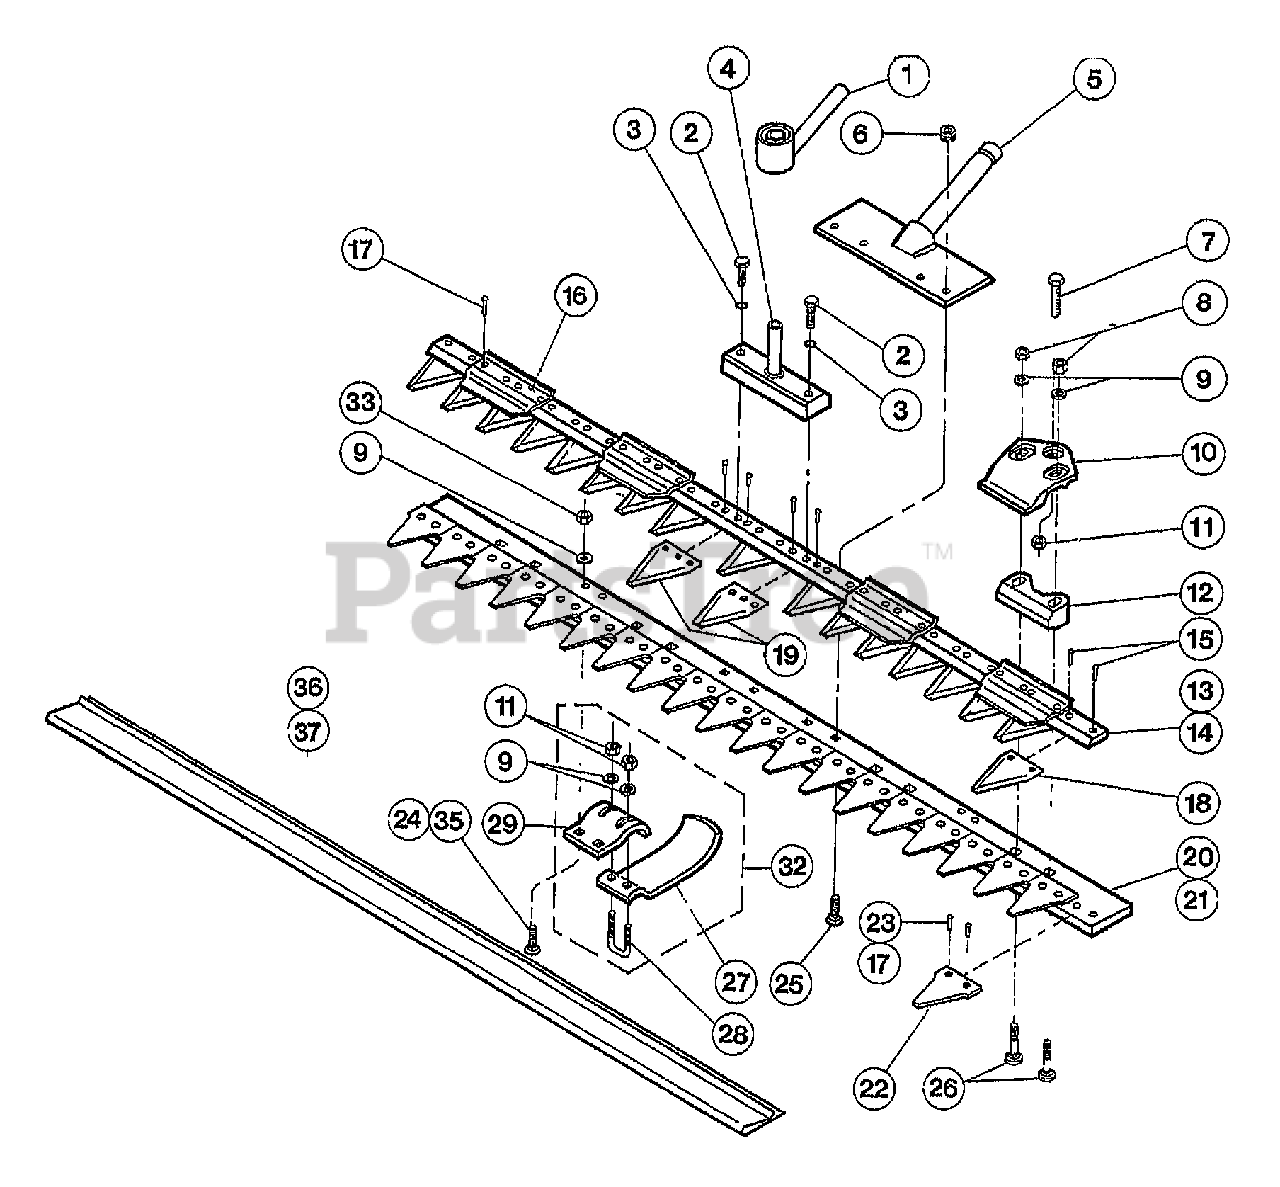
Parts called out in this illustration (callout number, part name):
1	ASSM-DRIVE SOCKET
2	SCR-HH M8X25 CL 10.9
3	WASHER-LK .312 EXT TOOTH
4	PIN-BAR MNT PNT #40088P
5	MOUNT-CUTTERBAR #40083P
6	NUT-H/LK 5/16-18 NYLOCK
7	SCR-HH M8 X 30
9	WASHER-FLAT 5/16 SAE
10	CLIP-BLADE GUIDE
11	NUT-M8 BRAKE
12	PLATE
13	ASSM-34" BLADE T/B SICKLEBAR
14	ASSM-38" KNIFE T/B SICKLEBAR
15	RIVETS, 5.3MM x 14MM, FOR 38-INCH BAR
15	RIVETS, 5.3MM x 14MM, FOR 34-INCH BAR
16	PLATE-WEAR
17	RIVETS, 5.3MM x 16MM, FOR 38-INCH BAR
17	RIVETS, 5.3MM x 16MM, FOR 34INCH BAR
18	BAR-CUTTER 2 HOLE BLADE SECTION
19	BLADE-SECTIONS 3 HOLES
20	BAR-LEDGER ASM W/BLADES
21	LEDGER BAR W/RIVET BLADE
22	BLADE, LEDGER BAR
24	SCR-CARR M8X30MM SQNK
25	SCR-CARR 5/16-18X1.25 G5
26	SCR-CARR M8X1.25X45
27	BOTTOM HEIGHT ADJ
28	BOLT-U M8 HEIGHT ADJUST
29	TOP HEIGHT ADJ
32	ASSM-ADJUSTABLE SKID
33	NUT-NYLOC M8
35	SCR-CARR M8X30MM
36	COVER-100CM BLADE
37	SHIELD-PLASTIC CUTTERBAR
